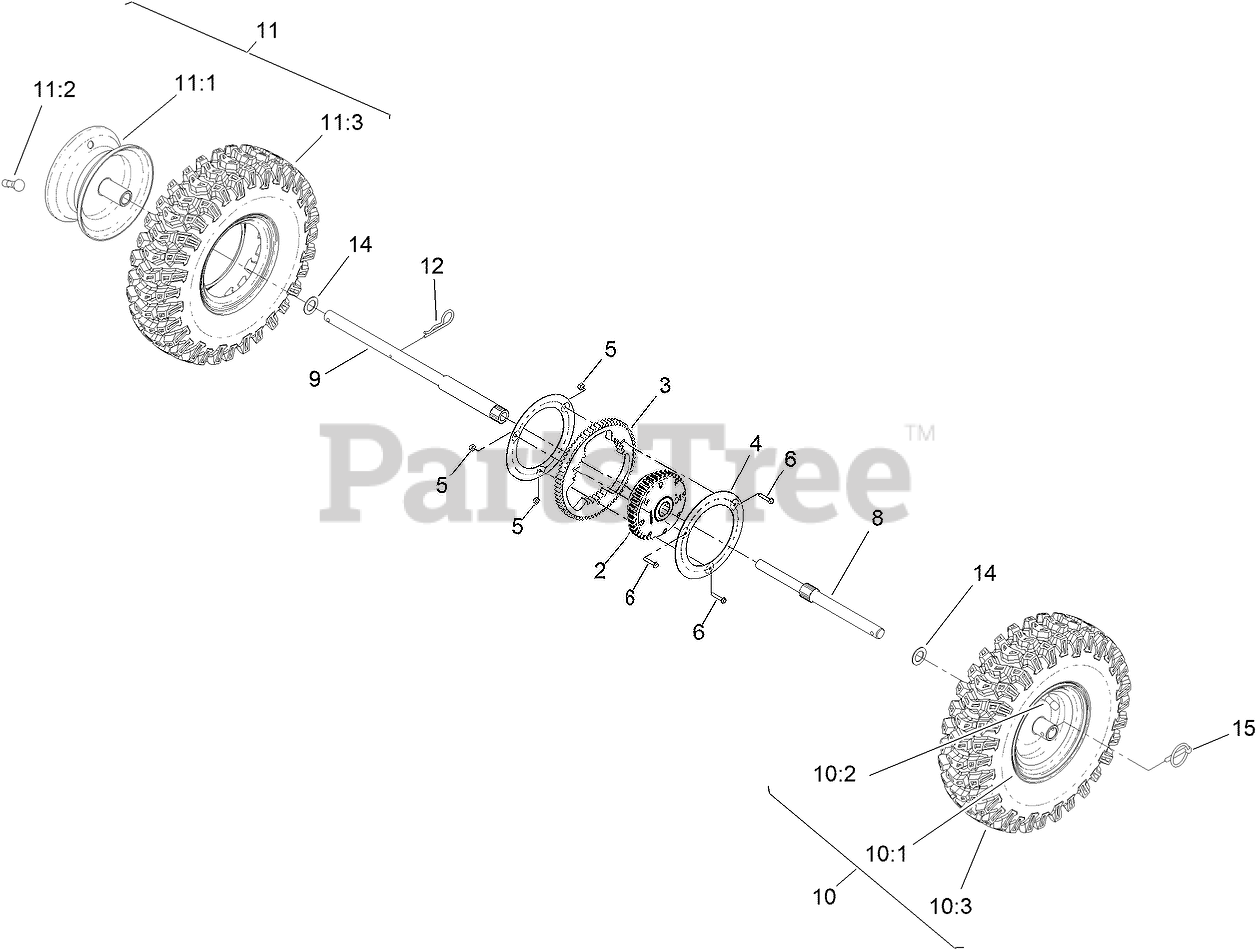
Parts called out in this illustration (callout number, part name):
2	TRANSMISSION
3	GEAR-AXLE
4	PLATE-GEAR
5	NUT-HEX
6	SCREW-HWH
8	AXLE-LT, CTS
9	AXLE-RT, CTS
10	LH WHEEL AND TIRE ASM
10:1	WHEEL (15X4 TIRE)
11	RH WHEEL AND TIRE ASM
11:1	WHEEL (15X4 TIRE)
12	PIN-HAIR
14	WASHER-THRUST
15	KLIK PIN ASM
